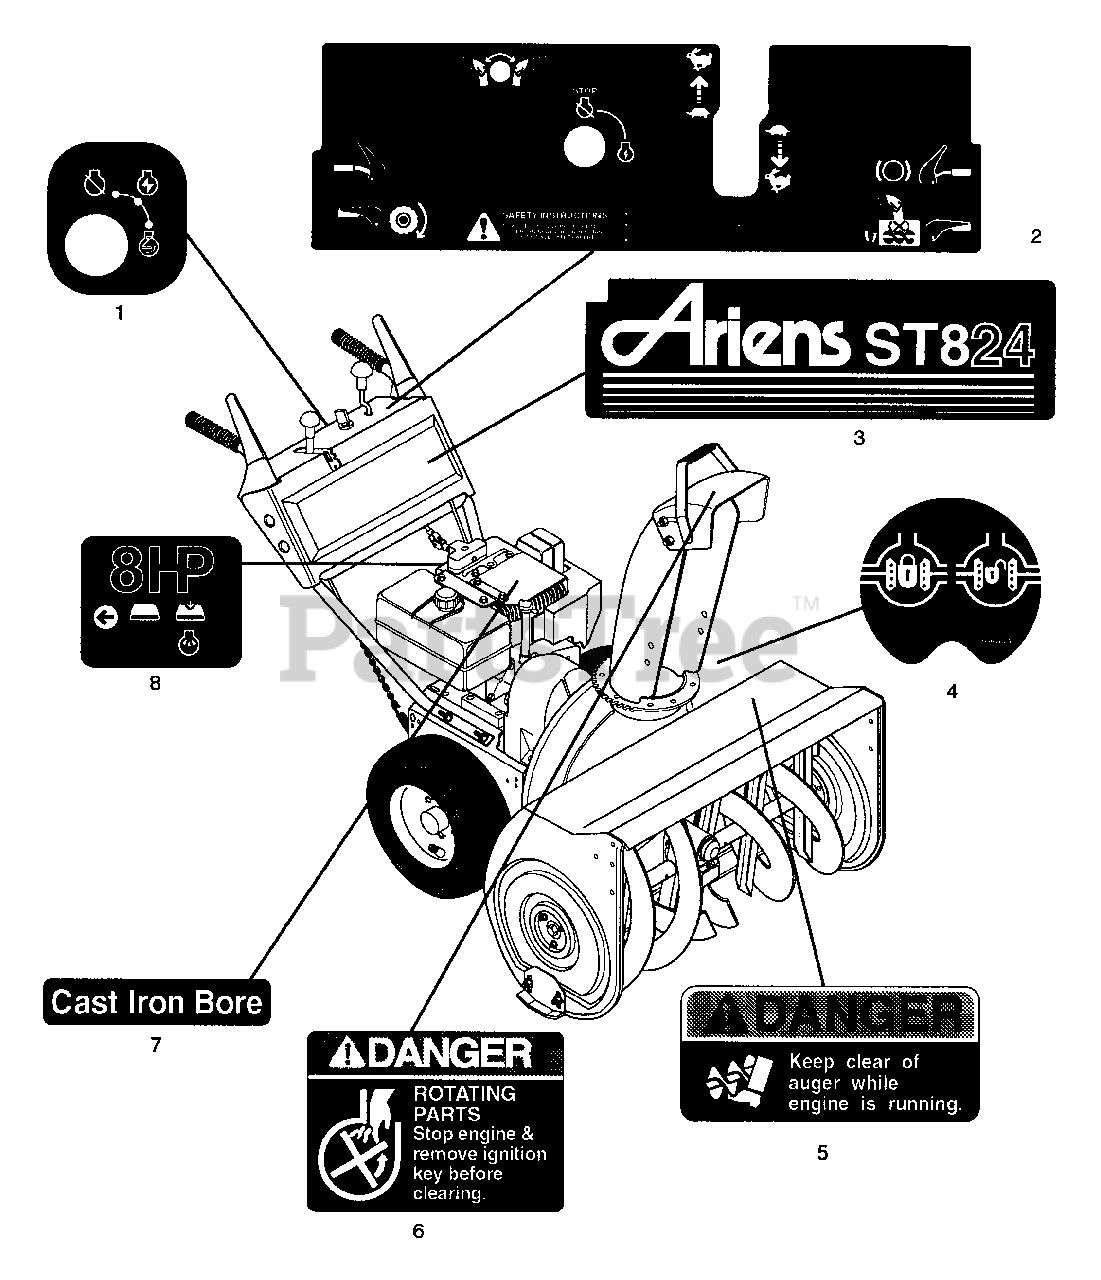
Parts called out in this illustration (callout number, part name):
1	DECAL 924-SWITCH
2	DECAL-DASH
3	DECAL 824
4	DIFFERENTIAL LOCK DECAL
5	DECAL - DANGER
6	DECAL-DANGER ROTATING PARTS
7	DECAL - CAST IRON BORE
8	DECAL 8 HP & PRIMER
